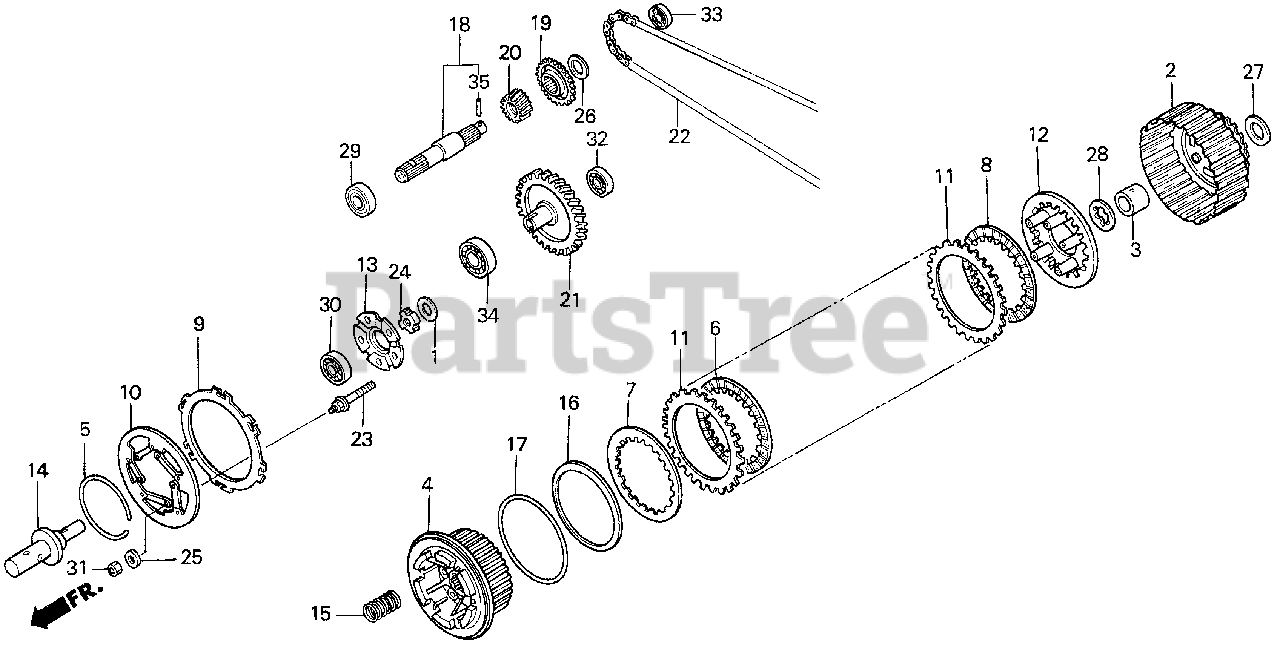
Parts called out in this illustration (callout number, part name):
1	WASHER, OIL FILTER ROTOR LOCKING
2	CLUTCH (OUTER)
3	GUIDE, CLUTCH (OUTER)
4	CENTER, CLUTCH
5	SET-RING (100.5MM)
6	DISK A, CLUTCH FRICTION
7	DISK A, CLUTCH FRICTION
8	DISK B, CLUTCH FRICTION
9	PLATE B, BRAKE
10	PLATE C, BRAKE
11	PLATE, CLUTCH
12	PLATE, CLUTCH PRESSURE
13	PLATE, CLUTCH LIFTER
14	ROD, CLUTCH LIFTER
15	SPRING, CLUTCH
16	SPRING, CONED DISK
17	SEAT, SPRING
18	SHAFT, INPUT
19	SPROCKET, DRIVE (31T)
20	GEAR, PUMP REDUCTION DRIVE (27T)
21	GEAR, PUMP REDUCTION DRIVEN (66T)
22	CHAIN, PRIMARY DRIVE
23	BOLT, SPECIAL (6X22)
24	NUT, LOCK (16MM)
25	WASHER (10MM)
26	WASHER, THRUST (17.2MM)
27	WASHER, THRUST (20MM)
28	WASHER B, SPLINE (20MM)
29	BEARING, RADIAL BALL U (60/20)
30	BEARING, RADIAL BALL (16003)
31	NUT, HEX. (5MM)
32	BEARING, RADIAL BALL (6202)
33	BEARING, RADIAL BALL (6003U)
34	BEARING, RADIAL BALL (6204U)
35	ROLLER (3X16.8)
